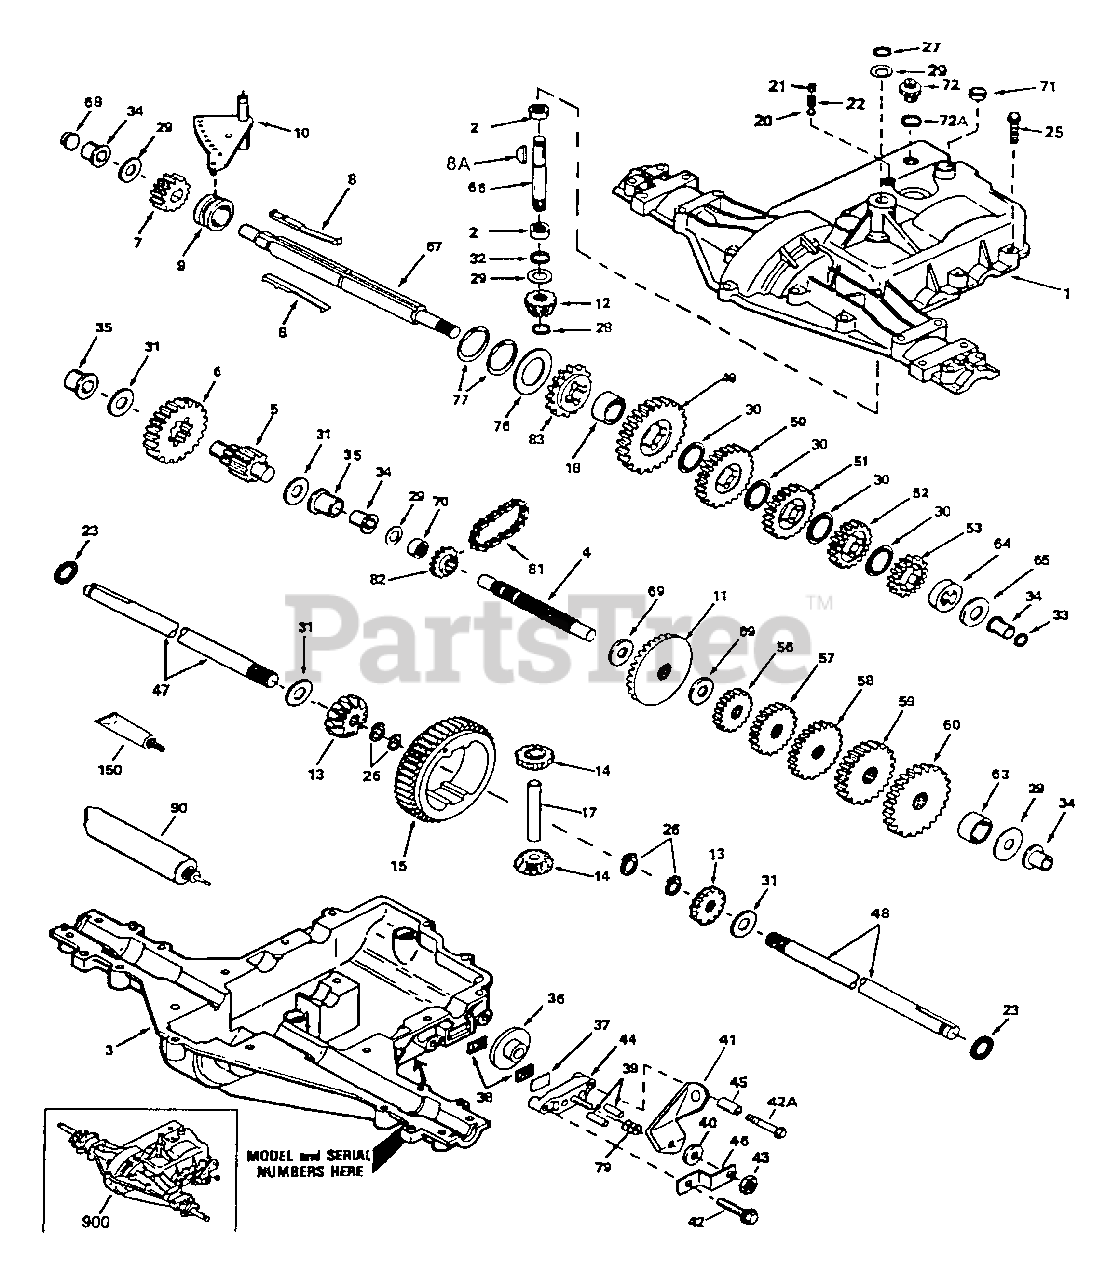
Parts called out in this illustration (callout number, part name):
1	Cover, Transaxle (Peerless part number)
2	Bearing, Needle (Peerless part number)
3	Case, Transaxle (Peerless part number)
4	Shaft, Counter (Peerless part number)
5	Shaft and Pinion Assembly, Output (Peerless part number)
6	Gear, Output (Peerless part number)
7	Gear, Spur, 15 Teeth (Peerless part number)
8	Key, Shift (Peerless part number)
8A	Key, Woodruff (Peerless part number)
9	Collar, Shifter (Peerless part number)
10	Rod and Fork Assembly, Shift (Peerless part number)
11	Gear, Bevel, 42 Teeth (Peerless part number)
12	Bevel Pinion, Input (Peerless part number)
13	Gear, Bevel (Peerless part number)
14	Gear, Bevel Pinion (Peerless part number)
15	Gear, Ring (Peerless part number)
17	Pin, Drive (Peerless part number)
18	Spacer, Neutral (Peerless part number)
20	Ball, Steel 5/16" diameter (Peerless part number)
21	Set Screw 3/8-16 x 3/8 (Peerless part number)
22	Spring (Peerless part number)
23	Ring, Seal (Peerless part number)
25	Screw, Flanged Hex Head, Thread Forming 1/4-20 x 1-1/4 (Peerless part number)
26	Ring, Retainer (Peerless part number)
27	Ring, Retainer (Peerless part number)
28	Ring, Retainer (Peerless part number)
29	Washer, Thrust (Peerless part number)
30	Washer, Thrust (Peerless part number)
31	Washer (Peerless part number)
32	"O" Ring (Peerless part number)
33	Seal, Square Cut (Peerless part number)
34	Bushing, Flanged (Peerless part number)
35	Bushing, Flanged (Peerless part number)
36	Disk, Brake (Peerless part number)
37	Plate, Brake Pad (Peerless part number)
38	Pad, Brake (Peerless part number) (AYP part number)
39	Pin, Dowel (Peerless part number)
40	Washer, Flat (Peerless part number)
41	Lever, Brake (Peerless part number)
42	Screw, Flanged Hex Head, Thread Forming 1/4-20 x 1-1/4 (Peerless part number)
42A	Screw 1/4-20 x 2-1/4 (Peerless part number)
43	Locknut 5/16-24 (Peerless part number)
44	Holder, Brake Pad (Peerless part number)
45	Spacer (Peerless part number)
46	Bracket, Brake Lever (Peerless part number)
47	Axle 11-5/16" long (Peerless part number)
48	Axle 16-1/2" long (Peerless part number)
49	Gear, Spur, 37 Teeth (1st) (Peerless part number)
50	Gear, Spur, 30 Teeth (2nd ) (Peerless part number)
51	Gear, Spur, 25 Teeth (3rd) (Peerless part number)
52	Gear, Spur, 22 Teeth (4th) (Peerless part number)
53	Gear, Spur, 19 Teeth, Steel (5th) (Peerless part number)
56	Gear, Spur, 12 Teeth (1st) (Peerless part number)
57	Gear, Spur, 20 Teeth (2nd) (Peerless part number)
58	Gear, Spur, 25 Teeth (3rd) (Peerless part number)
59	Gear, Spur, 28 Teeth (4th) (Peerless part number)
60	Gear, Spur, 31 Teeth (5th) (Peerless part number)
63	Spacer (Peerless part number)
64	Spacer (Peerless part number)
65	Washer, Thrust (Peerless part number)
66	Shaft, Input (Peerless part number)
67	Shaft, Brake, 4 Keyed (Peerless part number)
68	Plug (Peerless part number)
69	Washer, Thrust (Peerless part number)
70	Spacer (Peerless part number)
71	Seal, Square Cut (Peerless part number)
72	Plug, Threaded 9/16-18 (Peerless part number)
72A	"O" Ring (Peerless part number)
76	Washer, Thrust (Peerless part number)
77	Ring, Retaining, Inverted (Peerless part number)
79	Spring, Brake (Peerless part number)
81	Chain, Roller (Peerless part number)
82	Sprocket, 9 Teeth (Reverse) (Peerless part number)
83	Sprocket, 18 Teeth (Reverse) (Peerless part number)
90	Grease, Bentonite, 32 Ounce Bottle (Peerless part number)
150	Gasket Eliminator
900	Replacement Transaxle (Peerless part number)
